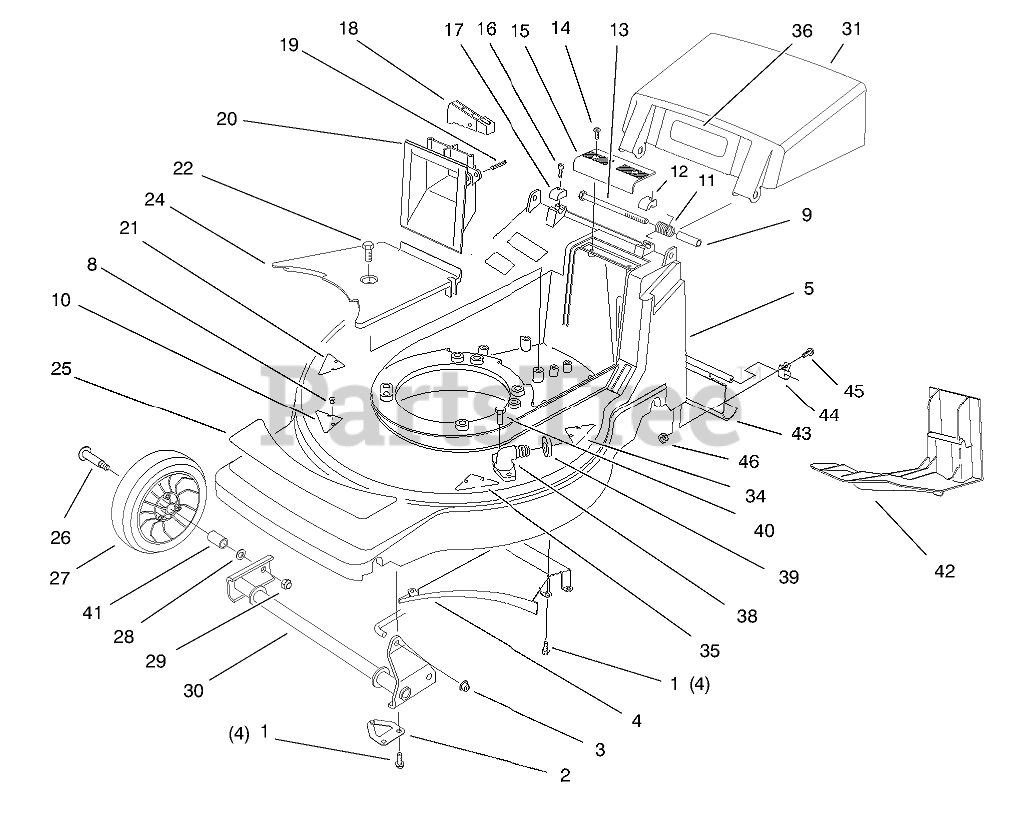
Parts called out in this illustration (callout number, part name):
1	SCREW-HWH
2	SHAFT RETAINER ASM
3	NUT-PUSH
4	Ramp-Discharge
5	Housing Assembly (Incl. Ref. #8, 10, 21, 25, 34, 35, 38-40)
8	SCREW-PPH
9	SPACER-DOOR
10	KICKER
11	SPRING-DOOR
12	CAP-HINGE BOLT, LH
13	SCREW-HH
14	SCREW-PPH, PLASTITE
15	GRIP-UPPER
16	SCREW-HSH
17	CAP-HINGE BOLT, RH
18	TRIGGER - HOC
19	PIN-SPIRAL
20	GRIP - LOWER
21	KICKER
22	SCREW-HWHTF
24	BELT COVER
25	DECAL - DECK
26	Bolt-Wheel
27	Wheel &Tire Assembly (Incl. Ref. #41)
28	WASHER
29	NUT-HEX
30	FRONT PIVOT WA
31	Discharge Door Assembly (Incl. Ref. #36)
34	KICKER
35	KICKER
36	DECAL-DANGER
38	FITTING-WASHOUT
39	O-RING
40	SCREW-HWH
41	BUSHING
42	DISCHARGE PLUG
43	SHIELD - TRAILING
44	HANGER - SHIELD
46	NUT-LOCK, NI
